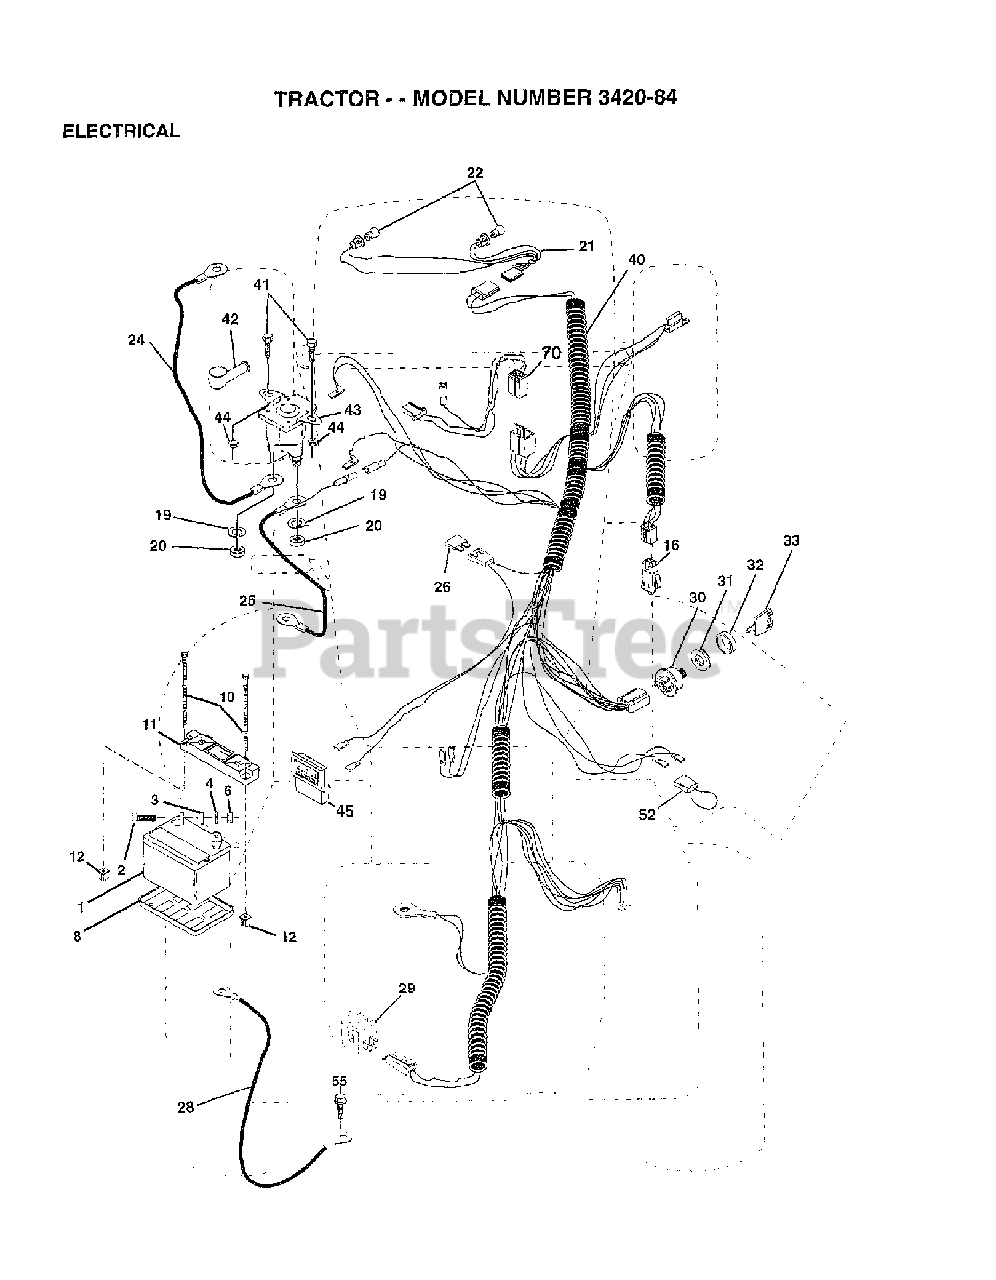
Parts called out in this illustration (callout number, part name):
3	WASHER
4	LOCKWASHER
6	NUT
8	TRAY.BATTERY
10	BOLT 1/4-20 X 7.5
11	BATTERY HOLDDOWN
20	NUT
22	LIGHTBULB
24	BATTERY CABLE
25	CABLE BATTERY 6 GA 22" W/16W
26	FUSE *
28	CABLE GROUND 6 GA 21" 90T BLK
29	SWITCH SEAT
30	SWITCH.IGNITION.4.POSITION
31	NUT
32	COVER KEY IGNITIO
33	KEY.MOLDED.GENERIC
41	BOLT
42	TERMINAL COVER
43	Solenoid Kit, .95
44	NUT.HEX.KEPS.1/4-20
45	AMMETER
52	WIRE PROTECTION LOOP
55	SCREW LT
70	HARNESS, ENGINE
